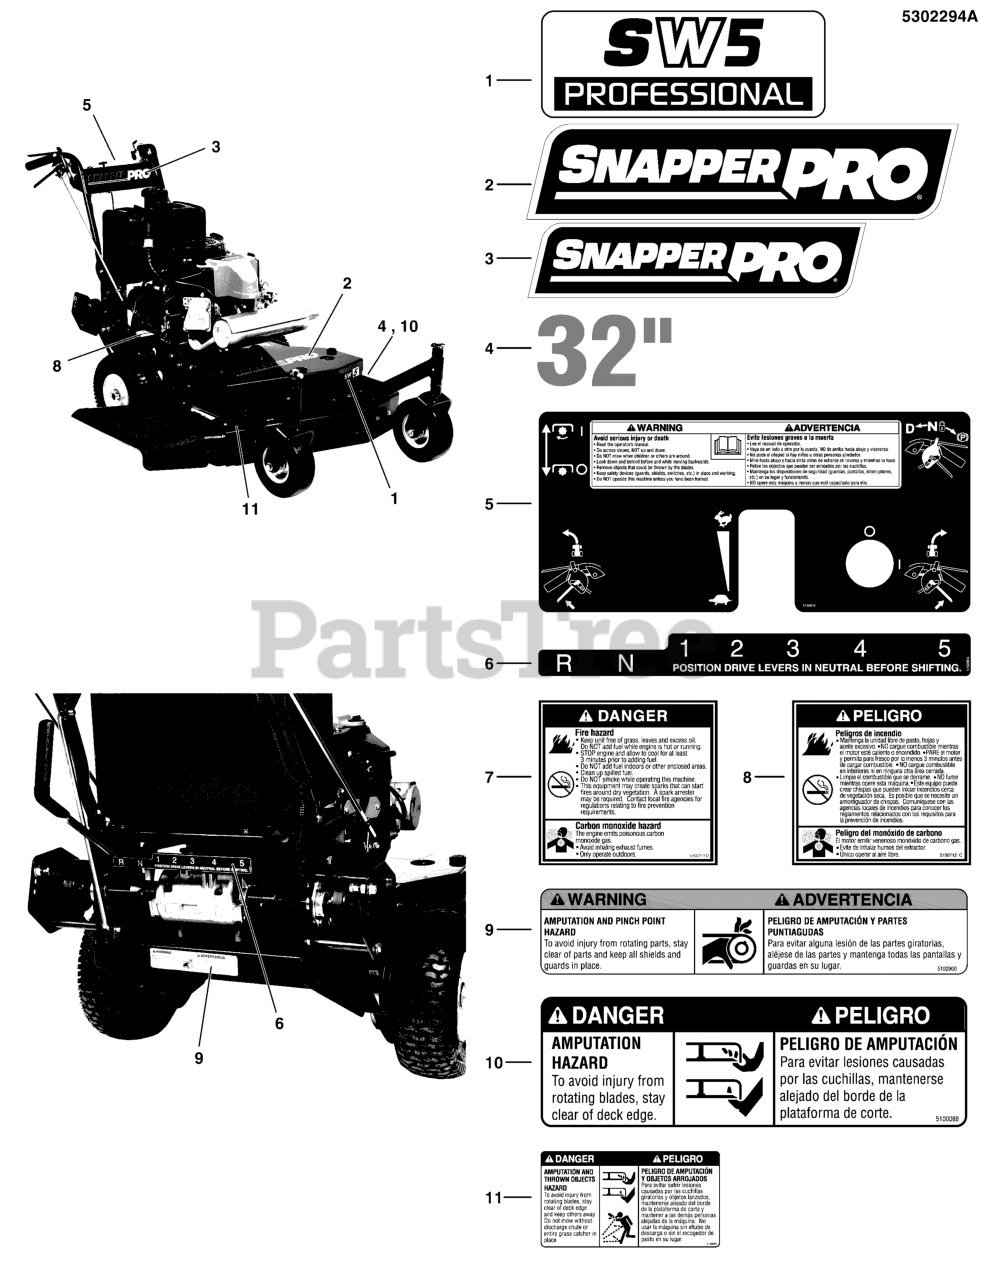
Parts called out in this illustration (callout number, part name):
1	DECAL, SW5 (2014)
2	DECAL, SNAPPER PRO LOGO, LARGE
3	DECAL, SNAPPER PRO LOGO, MEDIUM
4	DECAL, 32
5	DECAL, CONTROL PANEL, BELT DRIVE
6	DECAL, GEAR SELECTOR, BELT DRIVE
7	DECAL, DANGER
8	DECAL, DANGER, FIRE (SP)
9	DECAL, PINCH POINT
10	DECAL, DANGER, MOWER
11	DECAL, DANGER,MOWER DISCHARGE, 5.5 X 3.0
